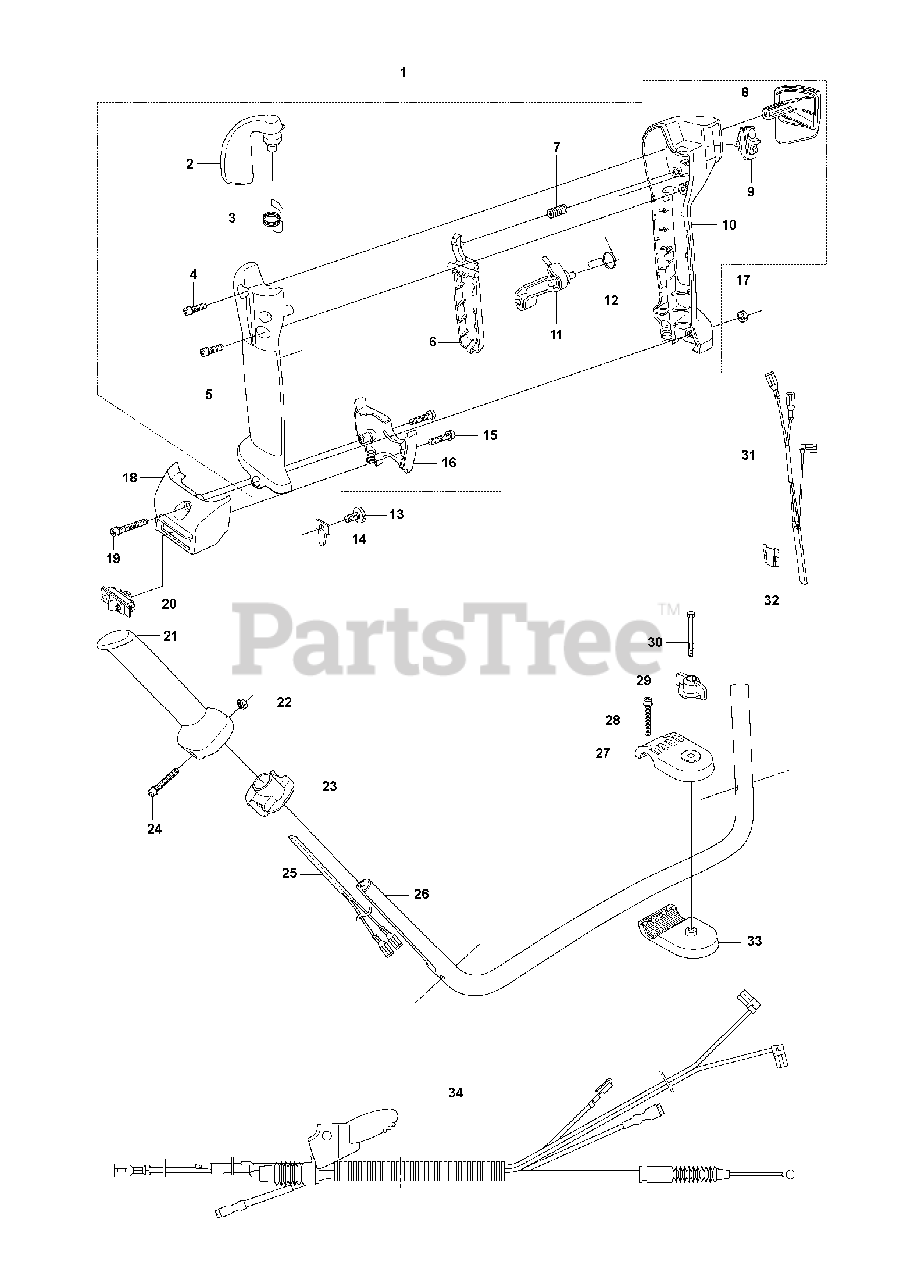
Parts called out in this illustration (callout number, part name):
3	RP SPRING
4	SCREW
7	SPRING
9	STOP BUTTON
10	HANDLE HALF RIGHT
11	LEVER
12	SPRING
13	SCREW
14	HOLDER
15	SCREW
17	NUT M6M M5
19	SCREW
20	SWITCH (G)
22	NUT M6M M5
23	HANDLE FASTENER
25	HEATING ELEMENT
26	RP HANDLE
26	%HANDLE
27	HANDLE BRACKET
30	%SCREW
31	HEATING ELEMENT
33	HANDLE BRACKET
34	RP WIRING ASSY
34	WIRING ASSY
